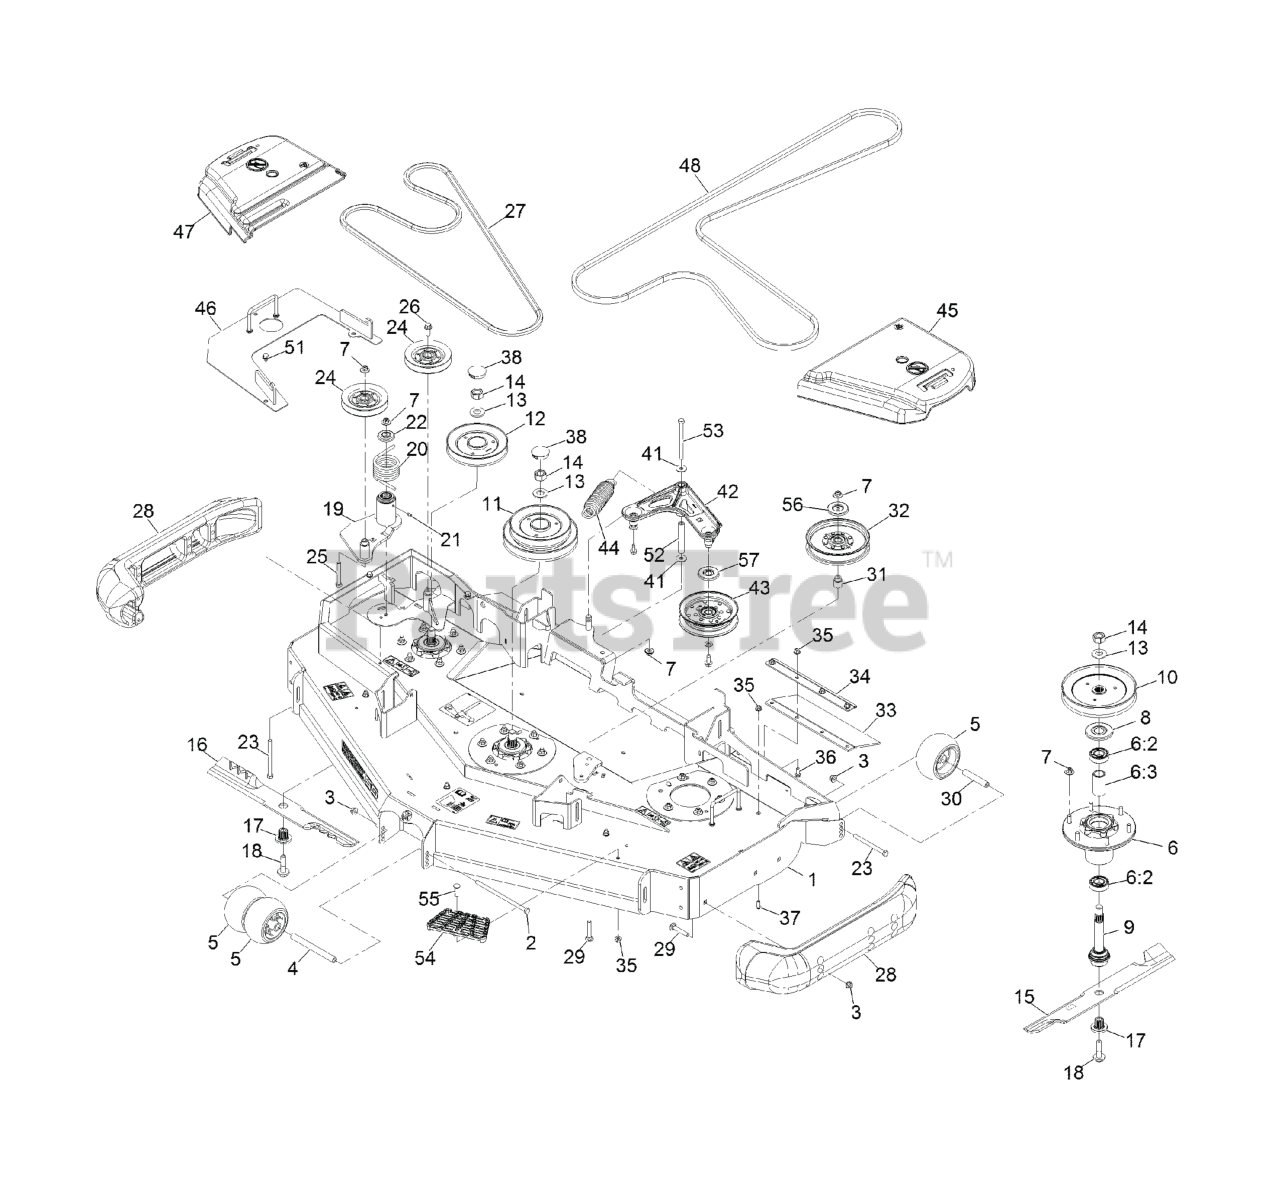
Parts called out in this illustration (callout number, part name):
1	ASM-DECK W/DECALS 60RD
2	SCREW-HH
3	NUT-HF, NI
4	SPACER-WHEEL
5	ROLLER-SCALP, ANTI
6	ASM-CUTTER HSG WITH BEARINGS
6:2	BEARING-BALL
6:3	SPACER-BEARING
7	Nut-Nyloc 3/8-16 Flg
8	GUARD,BEARING TOP .989
9	ASM-SPINDLE AND SEAL
10	SHEAVE,BLADE DRIVE 7.25
11	SHEAVE, DOUBLE 60RD
12	SHEAVE-RD REV DRIVE SERIES 4
14	NUT-HEX
15	Blade-Extreme 2, 20.50"
16	Blade-Low Lift 20.5, Rd60
16	Blade-Extreme 2-20.50, Rd60
17	BUSHING,SPLINED
18	SCREW,SEMS 1/2-20 X 2.19
19	IDLER ASM
20	SPRING-TORSION
21	FITTING-GREASE
22	GUARD-TOP
23	SCREW-HH
25	SCREW-HH
26	SCREW-HHF
27	BELT
28	SKID-BUMPER, DECK
29	Bolt-Carriage 3/8-16 X 2 1/4
30	TUBE-SPANNER
31	BUSHING-IDLER
32	IDLER-PULLEY, FLAT 6.00X1.00
33	GUARD-TIRE
34	SUPPORT-OUTER FLAP
35	NUT-HF, NI
36	SCREW-CARR
37	SCREW-HSBH
38	PLUG,BLACK NYLON 1.75
42	IDLER ARM ASM
43	IDLER-PULLEY, FLAT
44	SPRING-EXTENSION
45	COVER-BELT, LH
46	COVER-DRIVE, REVERSE
47	COVER-BELT, RH
48	BELT-V
52	BUSHING
53	SCREW-HH
54	STEP-DECK
55	Bolt-Carriage 5/16-18 X 1 1/4
56	SHIELD-DUST
57	SHIELD-GUARD, DUST
